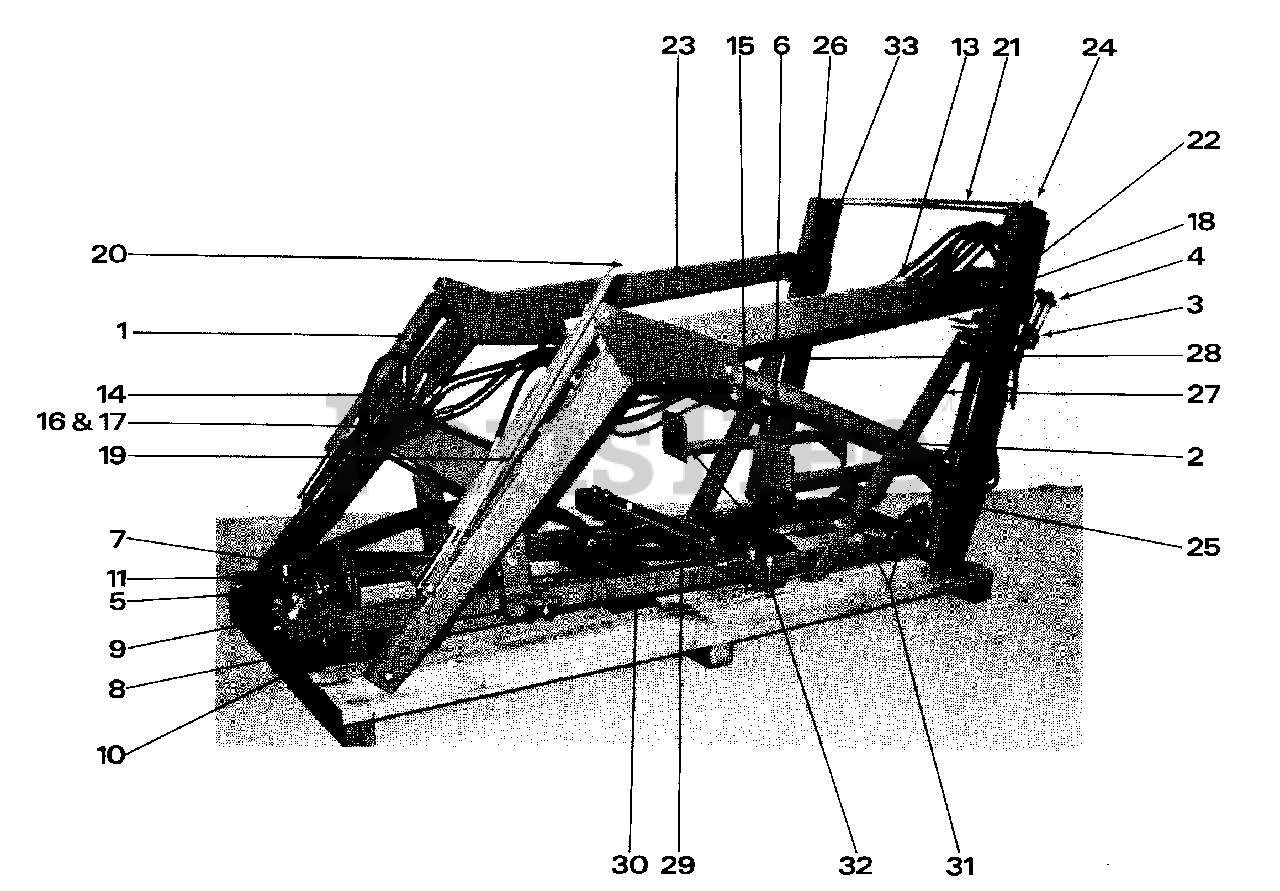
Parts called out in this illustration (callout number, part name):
1	Tilt Cylinders
2	Lift Cylinders
3	Control Valve
4	Valve Handles
5	Hydraulic Pump
6	Hose Clamps
7	Pump Mounting Assembly
8	Belt Tightner Assembly
9	Pump Guard
10	1/2" x 2 3/4" Hex Coupling Nut
11	Pulley
13	Lines to Control
14	Lines to Cylinders
15	Cylinder Lines
16	Hydraulic Line Brackets
17	Hydraulic Line Brackets
18	Lift Frame Pins
19	Bucket Guide Tube Assembly
20	Bucket Guide Rod Assembly
21	Stabilizer Bar
22	1/4" Straight Zert Fittings
23	Lift Frame Assembly
24	Breather & Filler Cap
25	Left Upright Assembly
26	Right Upright Assembly
27	Left Brace Arm
28	Right Brace Arm
29	Cross Member
30	Mounting Frame Assembly
31	Rear Hanger Brackets
32	Dismount Stands
33	Serial Number Plate
